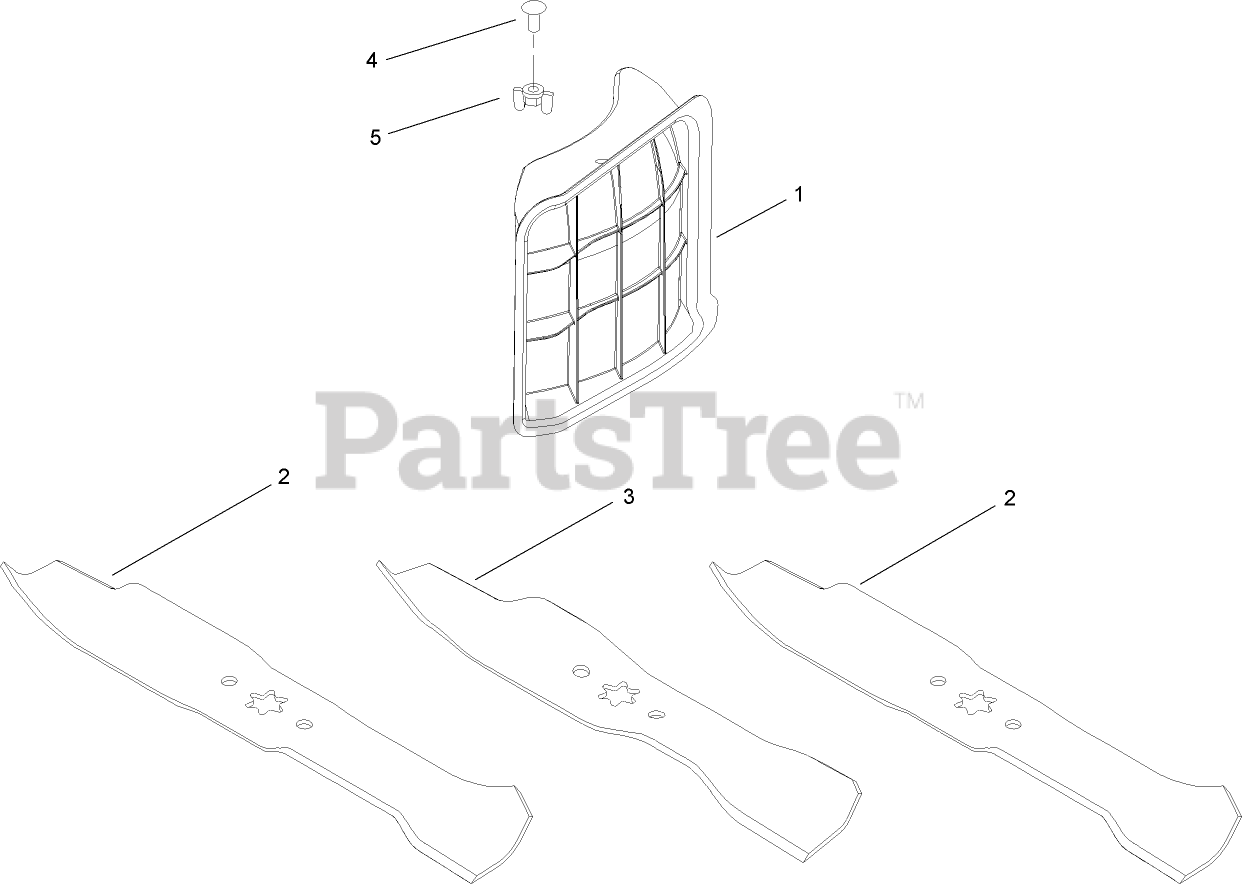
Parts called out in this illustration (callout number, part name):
1	PLUG-MULCH
2	BLADE-MULCHING (16.28)
3	BLADE-MULCHING (14.88)
4	SCREW-MACHINE
5	NUT-WING, PLASTIC
